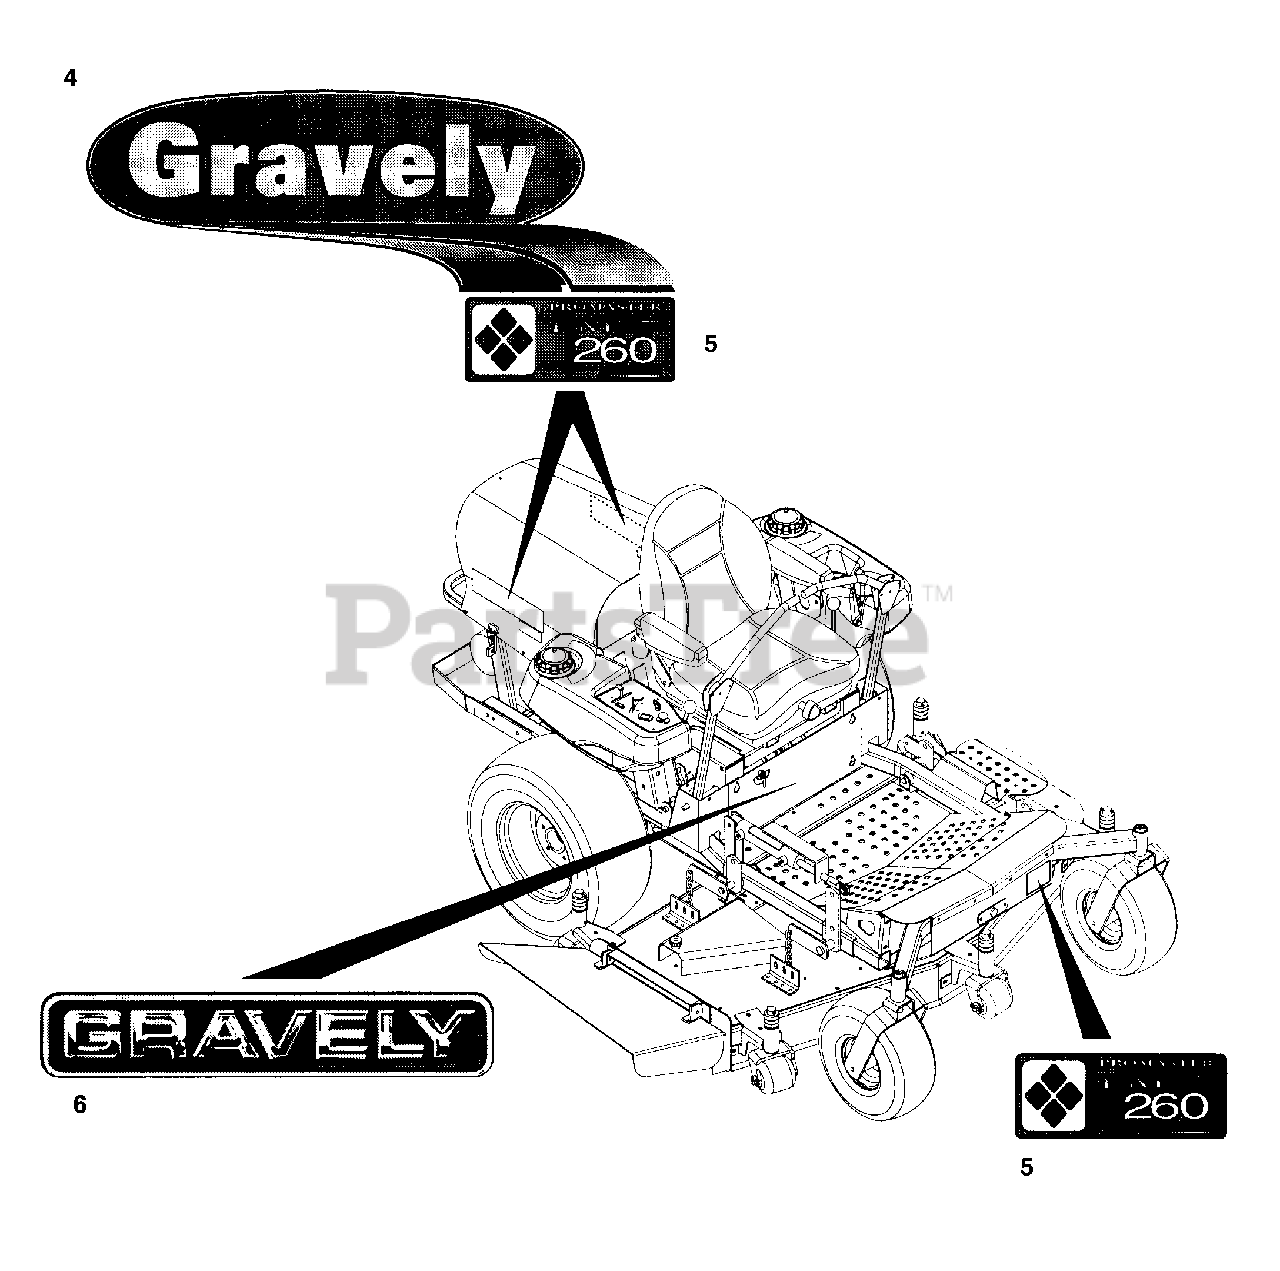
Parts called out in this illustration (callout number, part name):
4	Decal Set Gravely Logo
5	Decal-PM 260Z Logo
5	Decal-PM 250Z Logo
6	Decal-15" Gravely Logo
